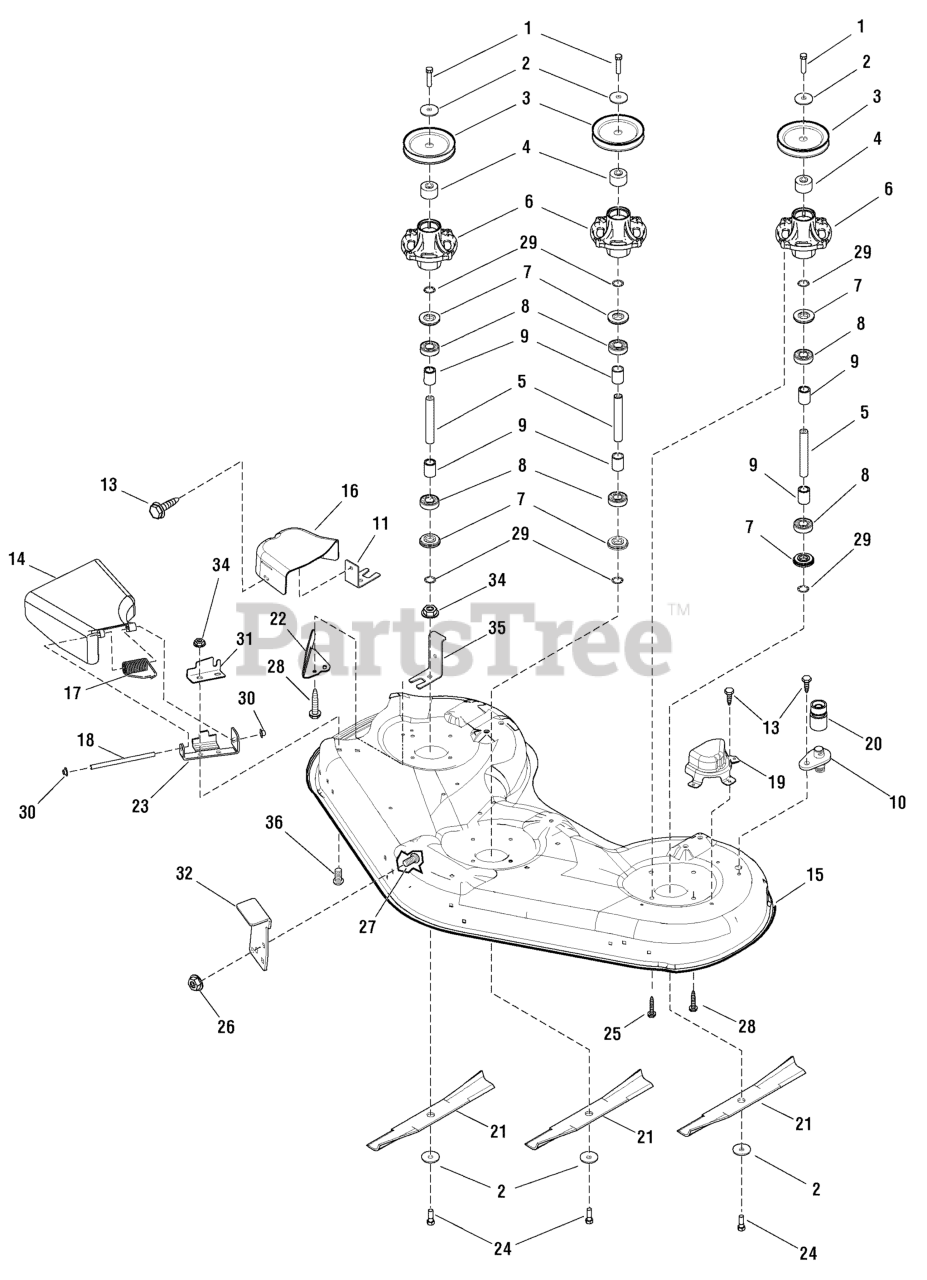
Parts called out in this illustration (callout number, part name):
1	CAPSCREW, Hex 7/16-14 x 1-3/4
2	WASHER, Spring, 3/4
3	PULLEY, 5.5", Split
4	SPACER, Pulley
5	SHAFT, Spindle, 20mm
6	HOUSING, Spindle
7	SHIELD, Arbor, 2"
8	BEARING, Ball, 20mm
9	SPACER, Bearing,
10	ADAPTER, Washout Port
11	BRACKET, Belt Cover, Front
13	SCREW, Hex Washer, Taptit, 5/16,18 x 3/4
14	DEFLECTOR, Discharge
15	HOUSING, Mower Deck, 52"
16	COVER, Belt
17	SPRING, Torsion Deflector
18	ROD, Deflector
19	COVER, Belt, Left
20	WASHOUT PORT, Connector
21	BLADE, Mower
22	BAFFLE, Pinchoff
23	HINGE, Deflector
24	CAPSCREW, Hex Head, 7/16-14 X 1
25	SCREW, Hex Washer Head, Taptit, 5/16-18 x 1-1/2
26	NUT, Hex Flange, 5/16-18
27	BOLT, Carriage, 5/16-18 x 7/8
28	SCREW, Hex Washer Head, Taptit, 5/16-18 x 1
29	RING, Self Locking
30	NUT, Push, 5/16
31	PLATE, Deflector Closeoff
34	NUT, Hex Flange, 5/16-18
35	BRACKET, Belt Cover, Rear
36	BOLT, Round Head Shoulder, 5/16-18 x 3/4
